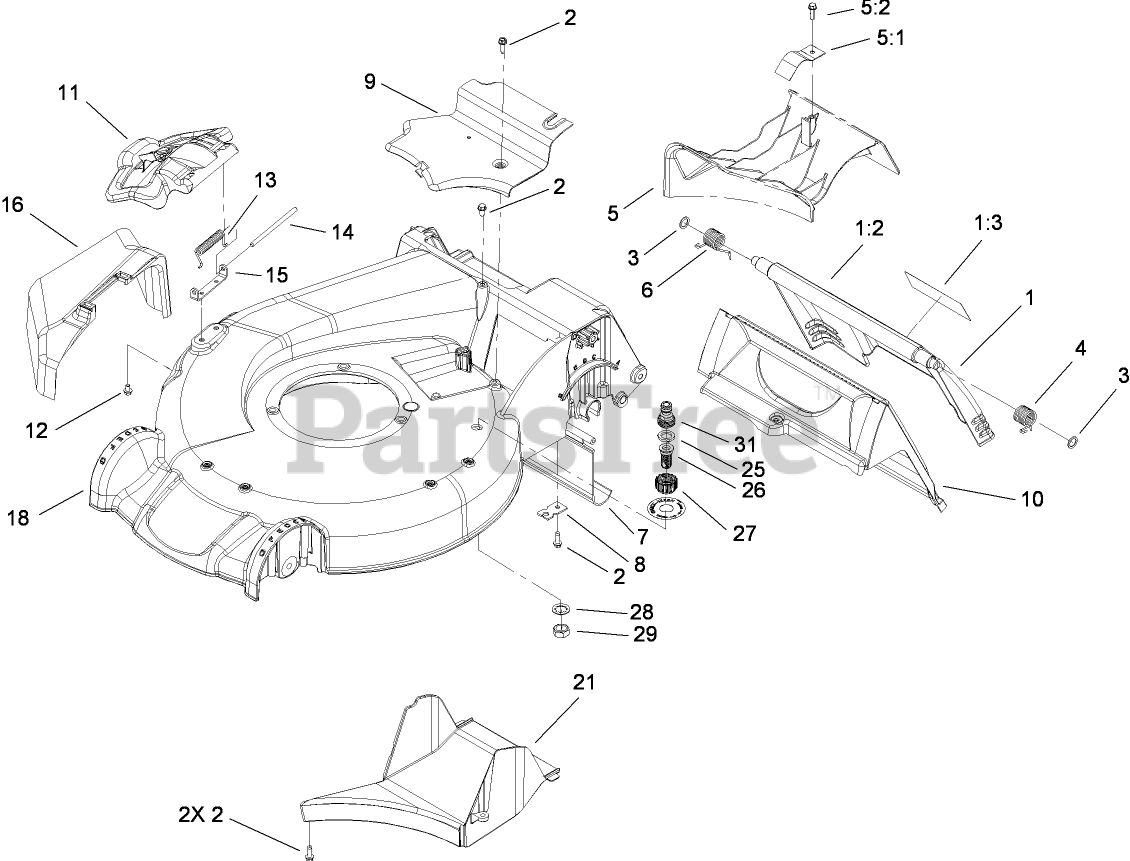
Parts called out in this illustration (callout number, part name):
1	REAR DOOR ASM
1:2	DECAL-WARNING
1:3	DECAL-WARNING
2	SCREW-HWHTF
3	WASHER-NYLON
4	SPRING-TORSION
5:2	SCREW-HWH
6	SPRING-TORSION
9	COVER-BELT
11	DISCHARGE DOOR ASM
12	SCREW-HWH
13	SPRING-TORSION
15	BRACKET-COVER
16	CHUTE-DISCHARGE, SIDE
18	HOUSING ASM
21	TUNNEL-DISCHARGE
25	WASHER-SEAL, WASHOUT PORT
26	PORT-WASHOUT
27	COUPLING-HOSE, WASHOUT PORT
28	WASHER-LOCK
29	NUT-JAM
31	ADAPTER-CONNECT, QUICK
